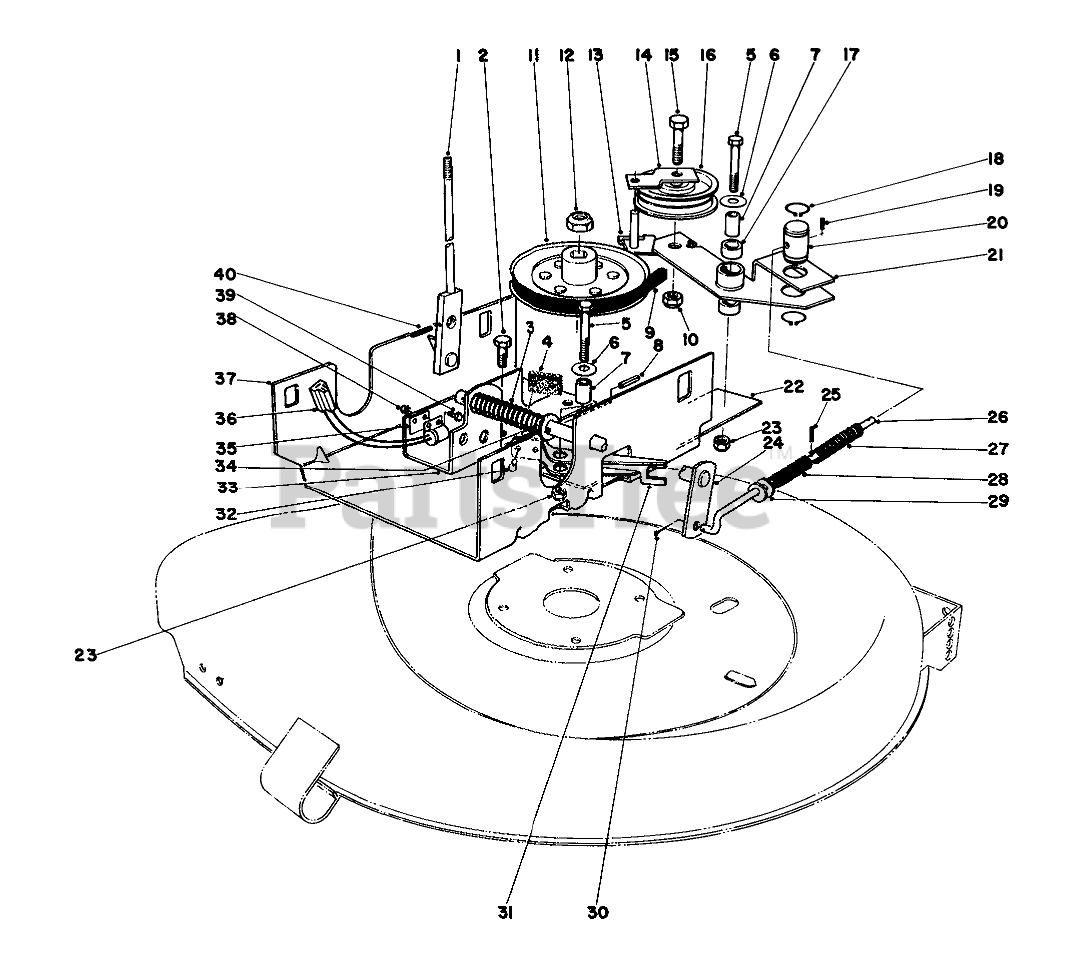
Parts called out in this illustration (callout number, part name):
1	Lever Deck Engagement
2	SCREW-HH
3	COMP SPRING O
4	BLADE BRAKE LINING
5	SCREW-HH
6	WASHER-PLAIN
7	PIVOT SPACER
8	PIN-SPRING
9	V-BELT
10	NUT-LOCK, SIDE
11	DECK PULLEY R
13	Belt Retainer
14	BELT RETAINER UPPER
15	SCREW-HH
16	Flat Idler
17	Bushing
18	RING-RETAINING
19	PIN-ROLL
20	Pin-Pivot
21	Idler Arm (Incl. Ref. #17)
22	Bracket Idler Mounting
23	NUT-LOCK, CONE
24	Linkage
25	PIN-SPRING
26	BLADE ENGAGE ROD
27	Spring Deck Idler
28	Spring Deck Brake
29	WASHER
30	PIN-COTTER
31	Blade Brake (Incl. Ref. #4 & 32)
32	Rivet
33	Mounting Bracket Blade
34	WASHER-FLAT
35	Spacer Switch
36	DECK INTERLOCK SWITCH
37	CHANNEL HT ADJ R
38	NUT-KEPS
40	PIN-SPIRAL
